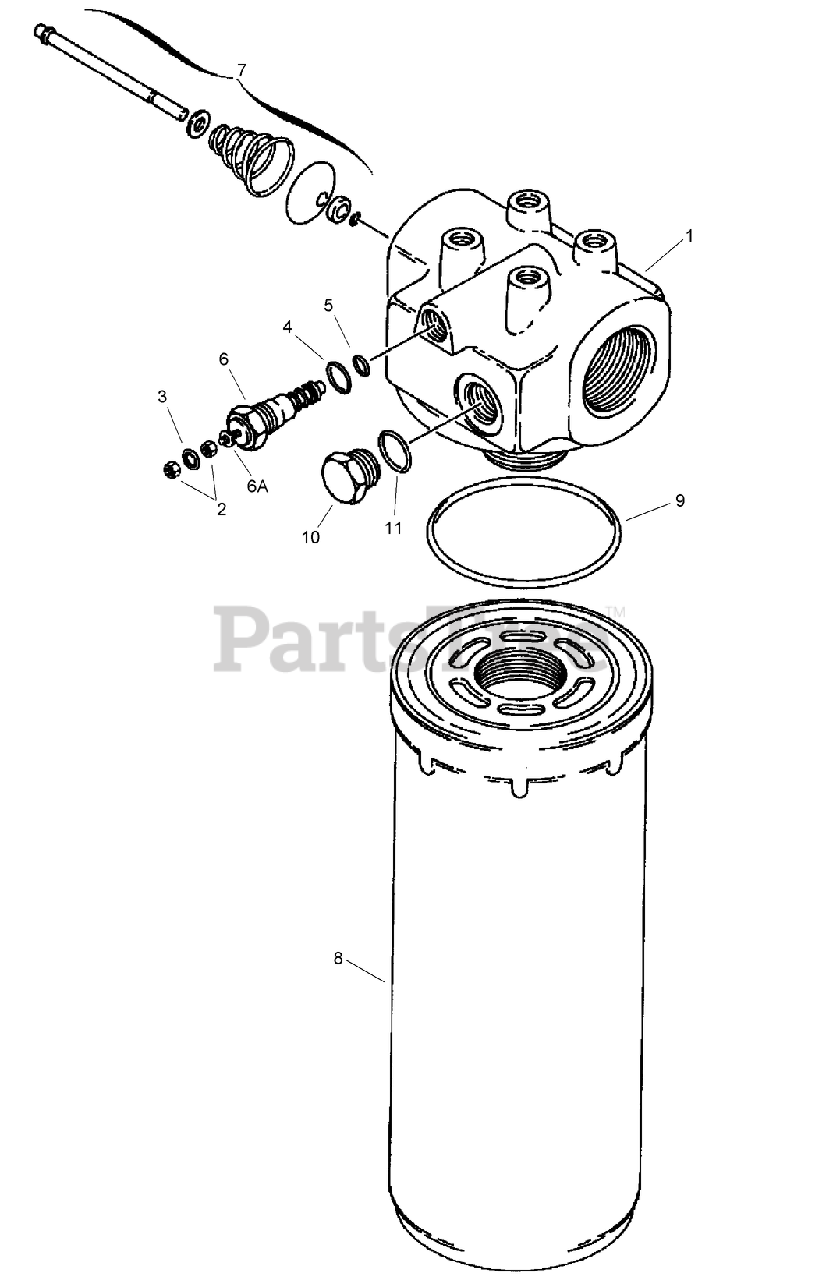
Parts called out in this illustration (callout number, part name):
1	Head-Filter
2	NUT-Hex, Left-hand Thread, No. 10 NF
3	WASHER-Internal Tooth Lock, 3/16 inch
5	O-RING-5/16 ID x 1/16 inch Wide, Small
6	INDICATOR-Restriction, Electric
6A	WASHER-Identification, Red/White Color
7	VALVE-Bypass, Filter
8	ELEMENT-Filter
9	O-RING-2-1/2 ID x 1/8 inch Wide, Filter Element to Head
10	PLUG-Hex Hd, ORB 3/8
